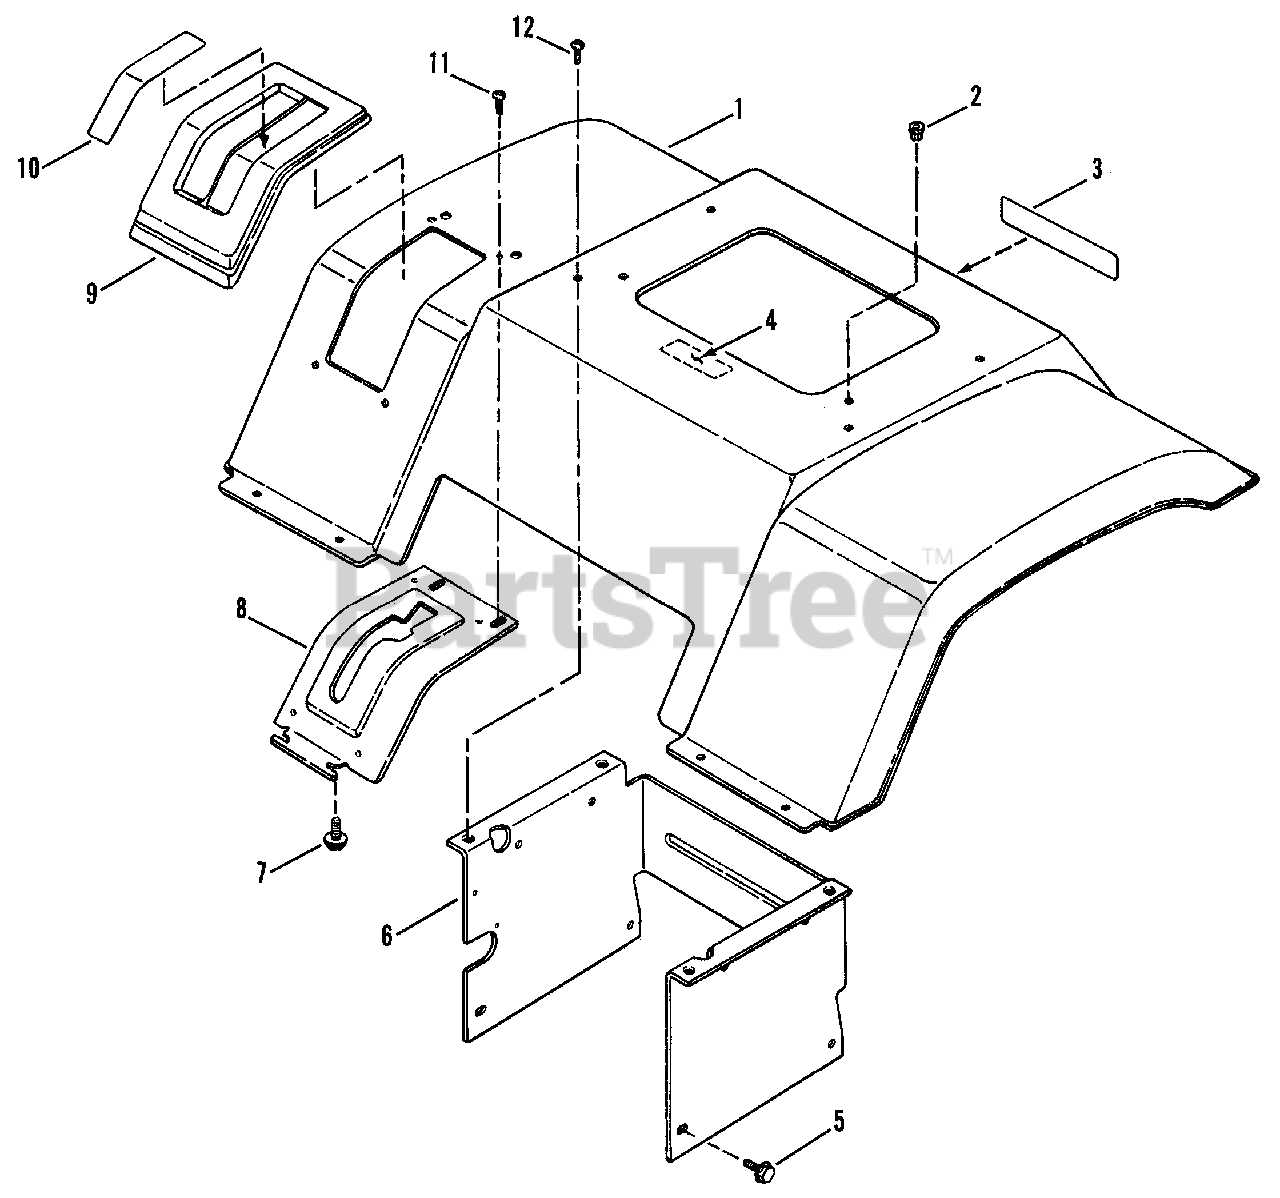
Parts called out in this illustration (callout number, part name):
1	PAN, Seat (Fender)
2	RIV-NUT, 5/16-18
3	DECAL - BLACKHAWK, Molded Logo
4	DECAL - CAUTION, Battery Location
5	SCREW, 5/16-18 x 5/8" Hex Washer Head, Self-Tapping
6	SUPPORT, Fender
7	SCREW, #10-16 x 1/2" Hex Washer Head, Self-Tapping
8	DETENT, Gear Shift
9	COVER, Shift
10	DECAL, Shift Cover, 5-Speed
11	SCREW, 1/4-20 x 5/8" Truss Head (Torx)
12	SCREW, 5/16-18 x 5/8" Truss Head (Torx)
